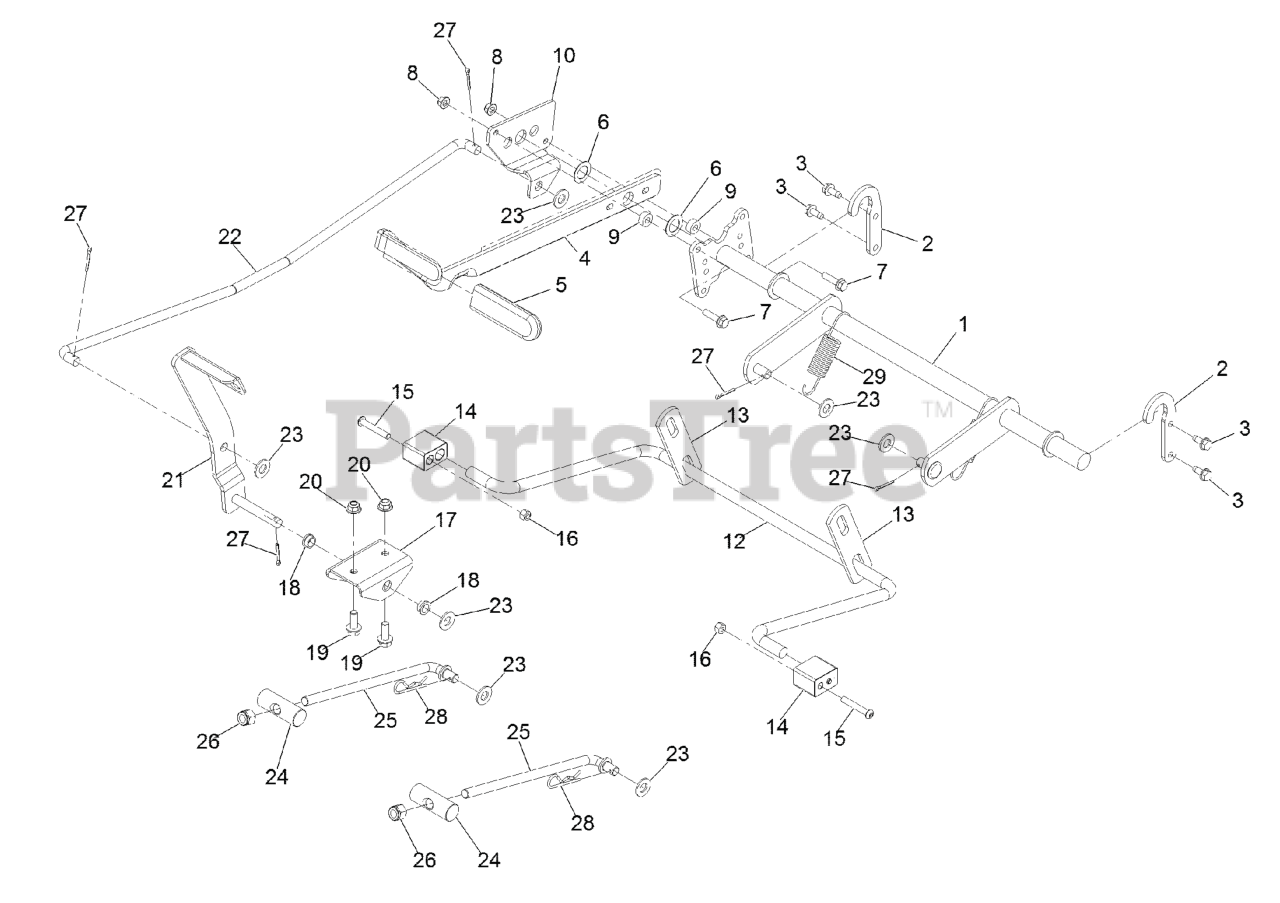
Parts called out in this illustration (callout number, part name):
1	DECK LIFT ASM
2	BRACKET-LIFT
3	Screw-HWH 5/16-18 X 3/4 Tf
4	HANDLE-DECK LIFT
5	GRIP-LEVER
6	WASHER-THRUST
7	SCREW-HHF
8	NUT-HF, NI
10	PLATE-FOOTLIFT
12	ARM-LIFT, REAR (WIDE)
13	LINK-LIFT
14	BLOCK-PIVOT
15	SCREW-HSBH
16	NUT-LOCK, NI
17	BRACKET-FOOTLIFT
18	BUSHING-FLANGE
19	SCREW-HHF 3/8-16 X 1
20	NUT-HF, NI
21	PEDAL ASM
22	ROD-FOOTLIFT
23	WASHER-FLAT
24	PIN-PIVOT
25	ROD-MOUNT, DECK
26	NUT-HEX
27	PIN-COTTER
28	PIN-COTTER
29	SPRING, EXTENSION
